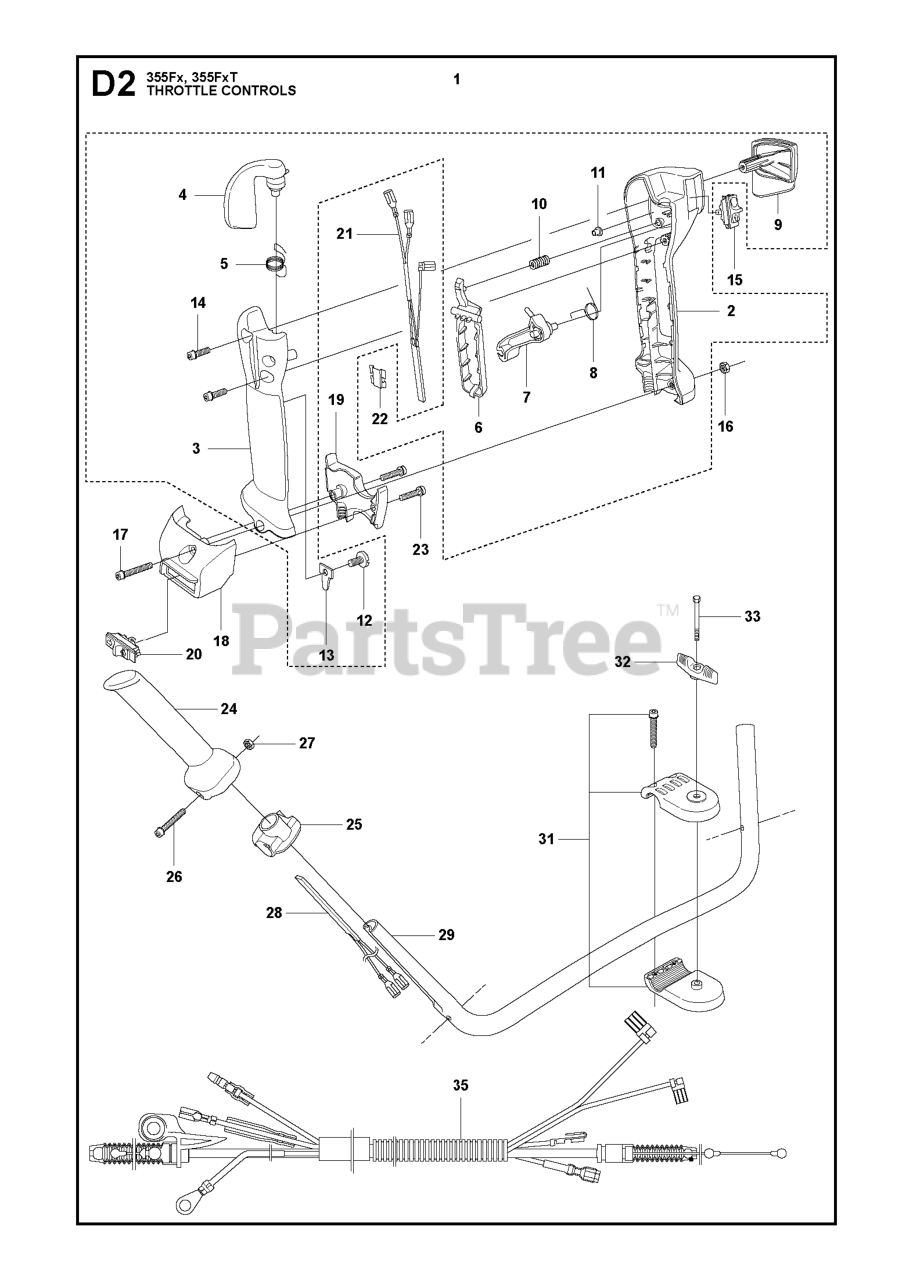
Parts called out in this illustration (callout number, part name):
1	THROTTLE HANDLE
2	HANDLE
3	HANDLE
4	THROTTLE TRIGGER
5	RP SPRING
6	THROTTLE LOCK
15	STOP BUTTON
16	NUT M6M M5
17	SCREW
18	HOLDER
19	HOLDER
20	SWITCH (G)
21	HEATING ELEMENT
23	SCREW
27	NUT M6M M5
28	HEATING ELEMENT
29	%HANDLE
31	HANDLEBAR BRACKET KIT
33	SCREW 6X70
35	WIRING
